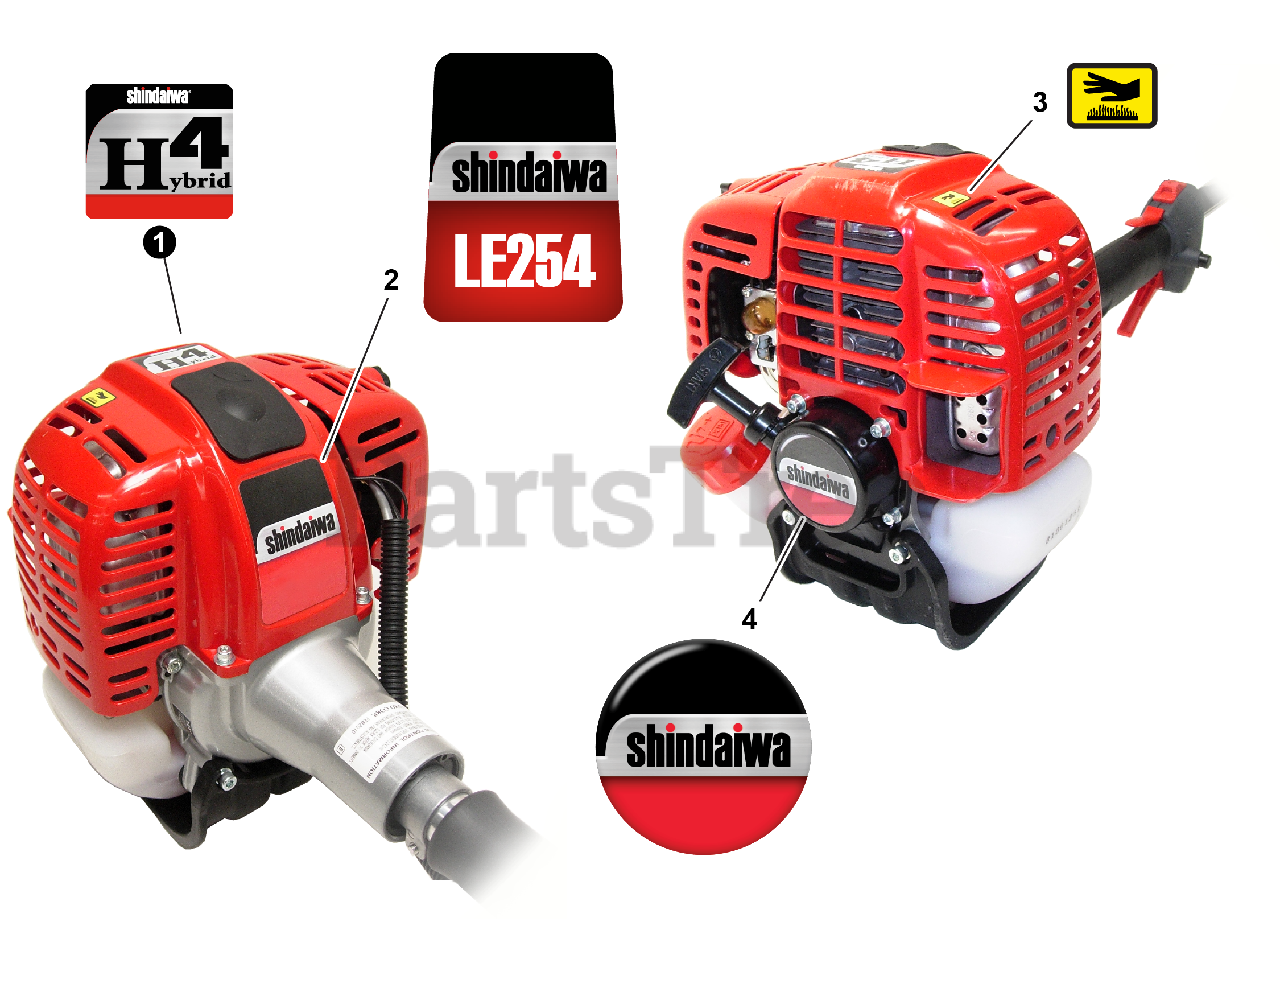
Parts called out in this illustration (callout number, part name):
1	LABEL, shindaiwa H4
2	LABEL, LE-254
3	LABEL, CAUTION - HOT
4	LABEL, RECOIL STARTER
